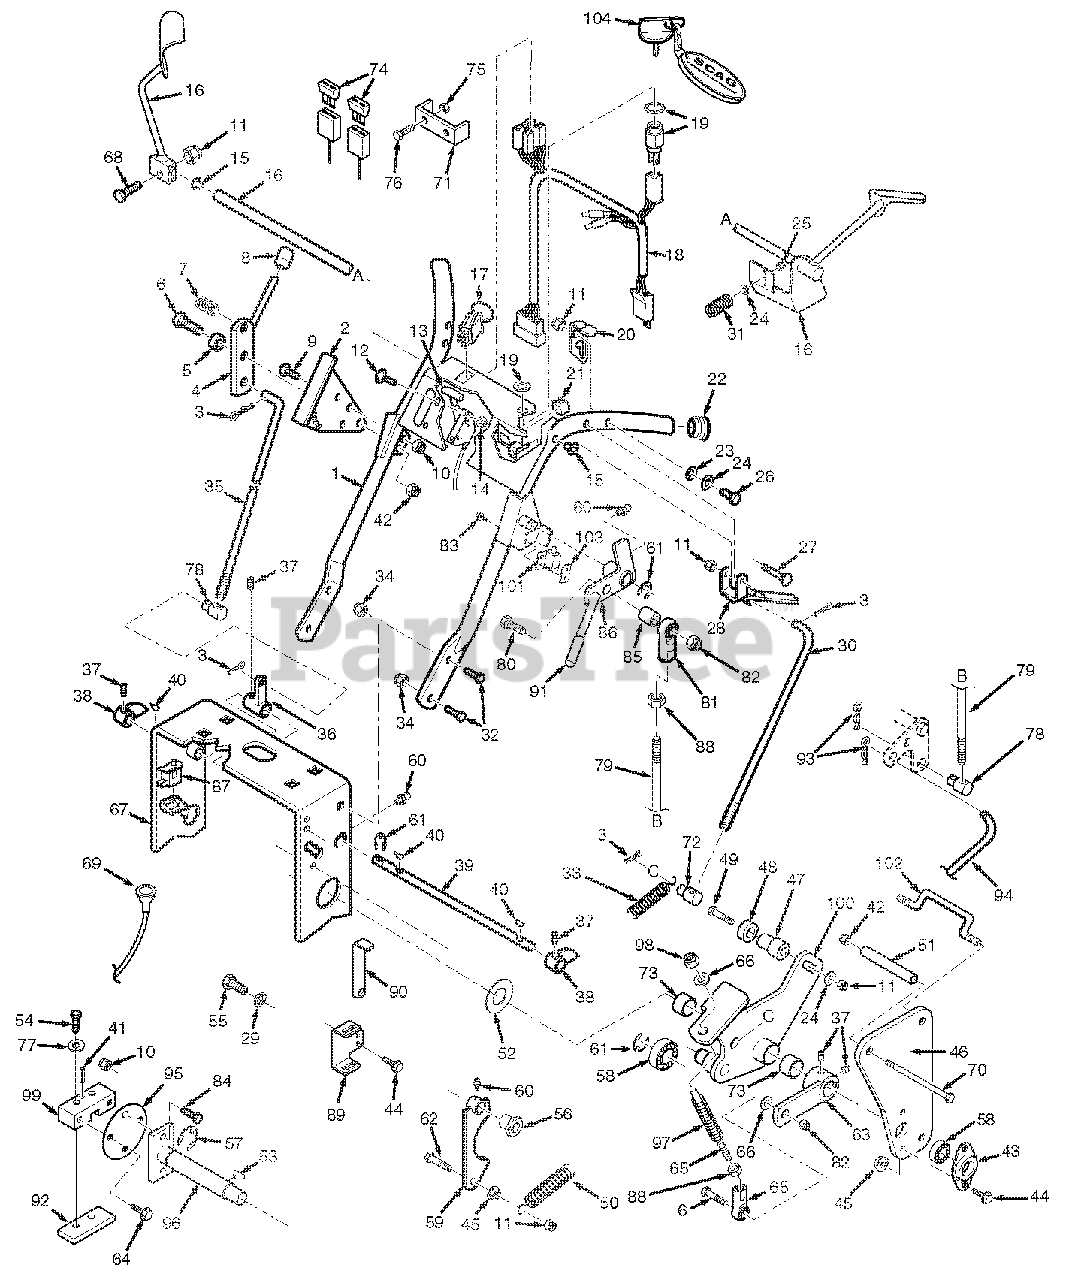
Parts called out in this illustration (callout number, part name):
1	Upper Handle Wlmt. W/Decals
2	Quadrant, Speed Control
3	Hairpin, .094 x 1.19
4	Lever, Speed Adjustment
5	Bushing, Speed Adjustment Lever
6	Hex Head Bolt, 3/8-16 x 1.5"
7	Ball Plunger
8	Knob, Speed Adjustment
9	Capscrew, 1/4-20 x 3/4" FHHS
10	Nut, 1/4-20 Elastic Stop
11	Nut, 5/16-18 Elastic Stop
12	Screw, #10-32 x 1/2" PW HD
13	Throttle Control
14	Nut, #10-32 Serr. Flange
15	Bushing
16	Handle, Oper. Presence-RH
16	Handle, Oper. Presence-LH
17	Switch, Electric Clutch Engage
18	Wire Harness, Manual Start
18	Wire Harness, Electric Start
19	Key Switch, Manual Srt.
19	Key Switch, Electric Srt.
20	Neutral Latch-RH
20	Neutral Latch-LH
21	Switch, Neutral Interlock
22	Plug, Handlebar
23	Washer, Curved Spring
24	Flat Washer
25	Nut, 5/16-18 Elastic Stop
26	Hex Head Bolt, 5/16-18 x 2"
27	Hex Hd. Bolt, 5/16-18 x 2.5"
28	Lever, Steering Control
29	Lockwasher, 3/8 Spring
30	Rod, Steering Control
31	Spring, Operator Presence
32	Capscr., 3/8-16 x 1" Ser. Flange
33	Spring
34	Nut, 3/8-16 Serr. Flange
35	Rod Speed Control
36	Bellcrank, Speed Control
37	Setscrew, 1/4-28 x .25"
38	Cam, Speed Control
39	Jackshaft, Speed Control
40	Key, 1/8 x 1/2" Woodruff
41	Roll Pin, 3/16-.75
42	Nut, Elastic Stop 3/8-16
43	Flange, Bearing
44	Capscrew, 5/16-18 x 1" Serr. Flg.
45	Nut, 5/16-18 Serrated Flange
46	Plate, Side
47	Spacer, Neutral Bearing
48	Bearing, Speed Ctrl. Bellcrank
49	Hex Head Bolt, 5/16-18 x 1-3/4"
50	Spring, Return
51	Spacer, Side Plate
52	Flatwasher, .766 x 1.25 x .035
53	Key, Woodruff, 3/16 x .75
54	Bolt, Hex Head, 1/4-20 x 1.25"
55	Bolt, Hex Head, 3/8-16 x 1"
56	Bushing, Brake
57	Clip, Retaining .750 diameter
58	Bearing, Ball Neutral Return
59	Cam, Neutral
60	Grease Fitting, 1/4-28 UNF
61	Retaining Ring, 5/8"
62	Hex Head Bolt, 5/16-18 x 1"
63	Lever, Speed Control
64	Bolt, Hex Head 1/4-20 x.75"
65	Linkage Assembly
66	Flat Wshr., 15/16 x .3906 x 12 ga
67	Deck, Engine 20" Wide
68	Hex Head Bolt, 5/16-18 x 1.25"
69	Choke Control
70	Bolt, Hex Head 3/8-16 x 4.25"
71	Fuse Holder - 21KAE
72	Swivel Joint, Steering Rod
73	Bushing
74	Blade Fuse, 20A - 22FSE
75	Nut, #10-32 Elastic Stop - 22FSE
76	Screw, #10-32 x 1.5" Phillips - 22FSE
77	Lockwasher, 1/4"
78	Swivel Joint
79	Rod, Brake Lever
80	Hex Hd. Bolt, 3/8-16 x 2"
81	Ball Joint, RH Thread
82	Nut, 3/8-16 Elastic Stop
83	Screw #10-32 Sltd Hex Wshr Hd
84	Bolt, 1/4-20 x .75"
85	Spacer
86	Parking Brake Lever w/Grip & Grease Fitting
87	Switch, Safety
88	Nut, 3/8-24
89	Mounting Bracket, Wrench
90	Wrench
91	Grip, Parking Brake
92	Plate, Threaded
93	Hairpin, .094 x 1.62"
94	Rod, Lower Brake
95	Plate, Coupler
96	Shaft, Pump Control
97	Spring
98	Nut, 3/8-16 Elastic Stop
99	Block, Pump Control
100	Control, LH
100	Control, RH
101	Switch, Parking Brake
102	Rod, Offset
103	Plate, Threaded
104	Key Chain with Keys
104	Key with Shroud
